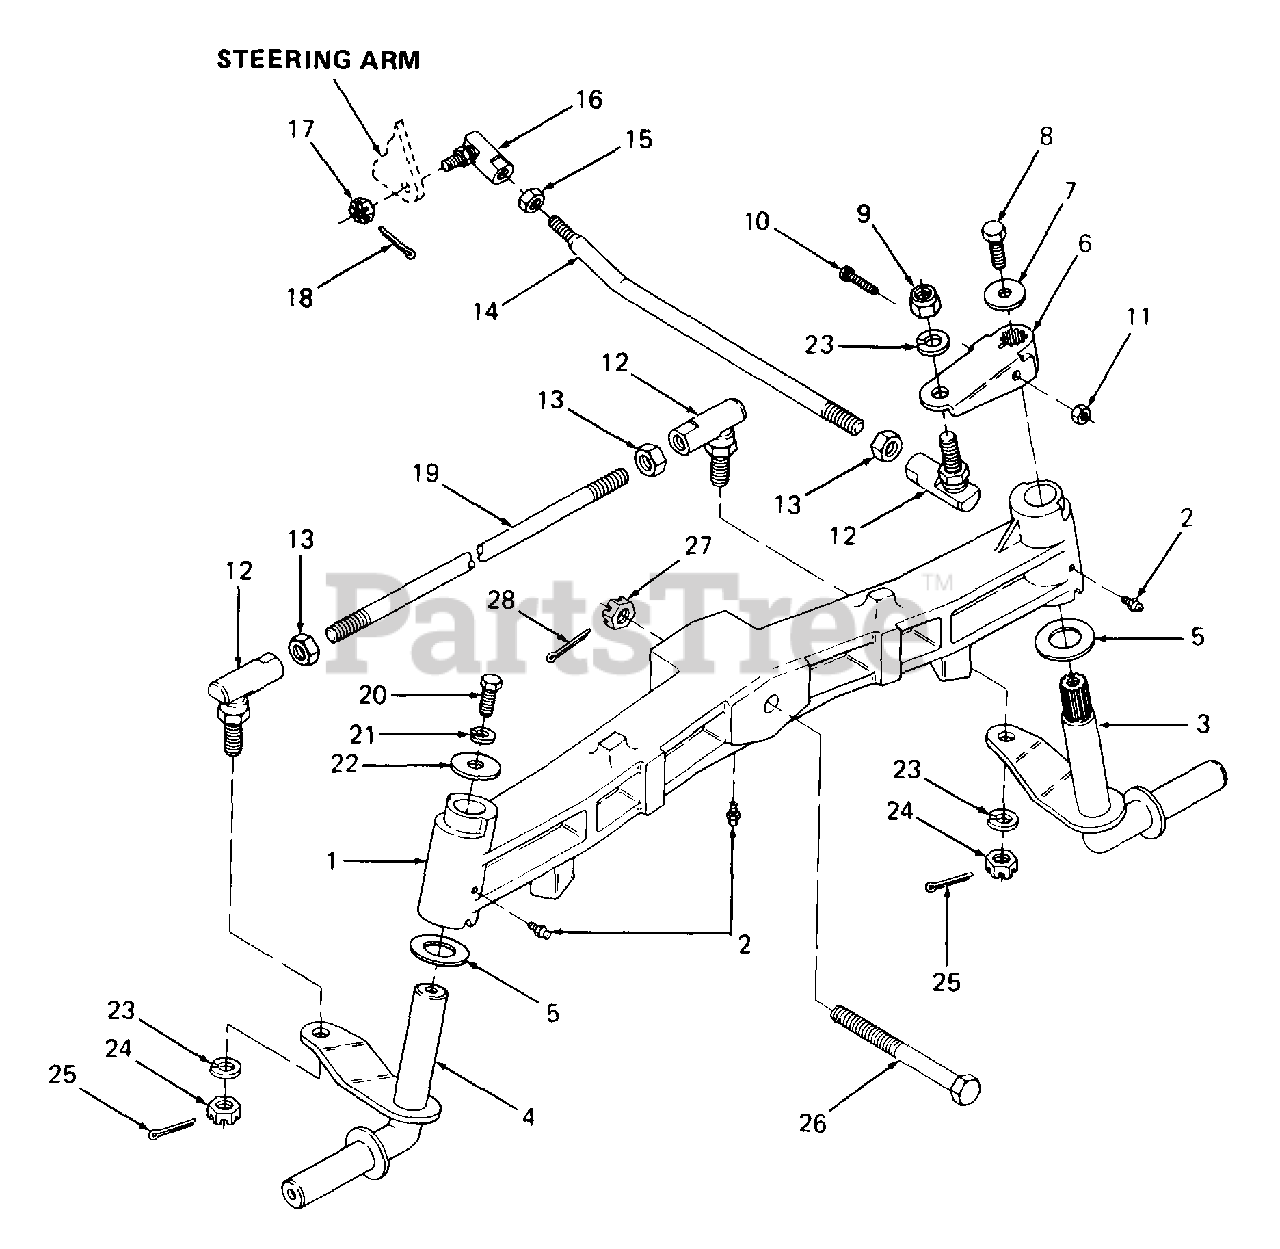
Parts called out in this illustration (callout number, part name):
3	Knuckle, Steering - LH
4	Knuckle, Steering - RH
5	Washer, Thrust, 1.03 X 1.62 X .03 Thk HDN
6	Arm, Steering
7	Washer, Flat, .406 X 1.25 X .157 Thk
8	Bolt, Hex Patch, 3/8-16 X 1.0 Lg GR5
9	Nut, Hex Top Lock, 1/2-20
10	Screw, Socket Hd Cap, 1/4-20 X 1.38 Lg
11	Nut, Hex Patch Lock, 1/4-20
12	Ball Joint
13	Nut, Hex Jam, 1/2-20 GR5
14	Link, Drag
15	Nut, Hex Jam, 3/8-24 GR5
16	Ball Joint
17	Nut, Hex Castle, 3/8-24 GR5
18	Pin, Cotter, 3/32 Dia X .75 Lg
20	Screw, Hex Cap, 3/8-16 X 1.0 Lg GR5
21	Washer, Lock, 3/8
22	Washer, Flat, .406 X 1.5 X .12 Thk
23	Washer Lock 1/2
24	Nut, Hex Castle, 1/2-20 GR5
25	Pin, Cotter, 3/32 Dia X 1.25 Lg
26	Bolt, Hex, 3/4-10 X 5.25 Lg GR5
27	Nut, Hex Castle, 3/4-10
28	Pin, Cotter, 1/8 Dia X 1.5 Lg
